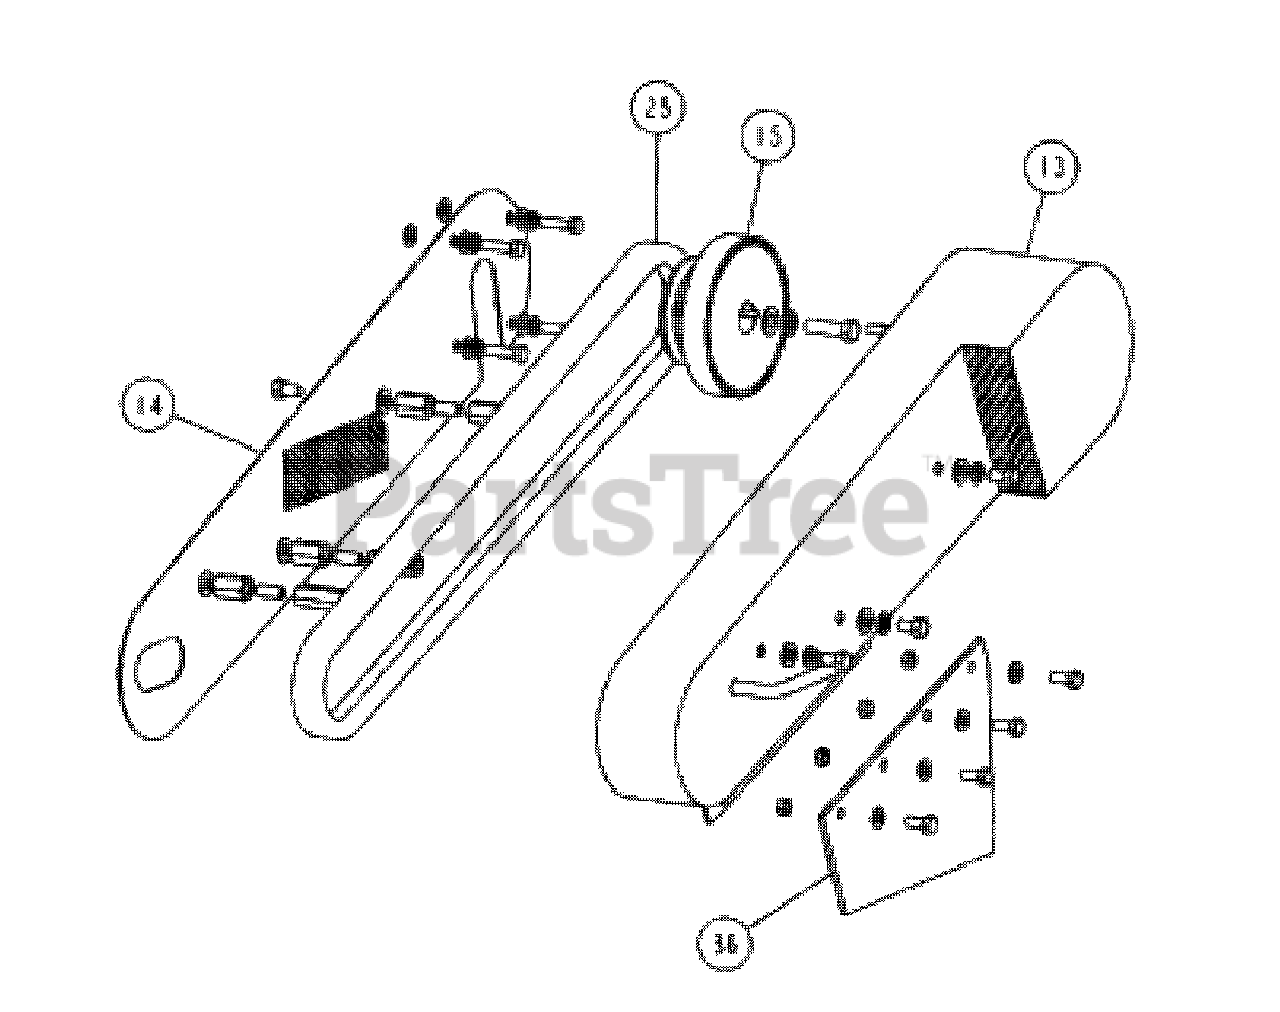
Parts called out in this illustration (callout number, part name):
13	Drive Cover Assembly
14	Belt Guard Plate
15	Centrifugal Clutch Assembly
25	Double V-Belt, BP54
36	Left Side Deflector Kit
